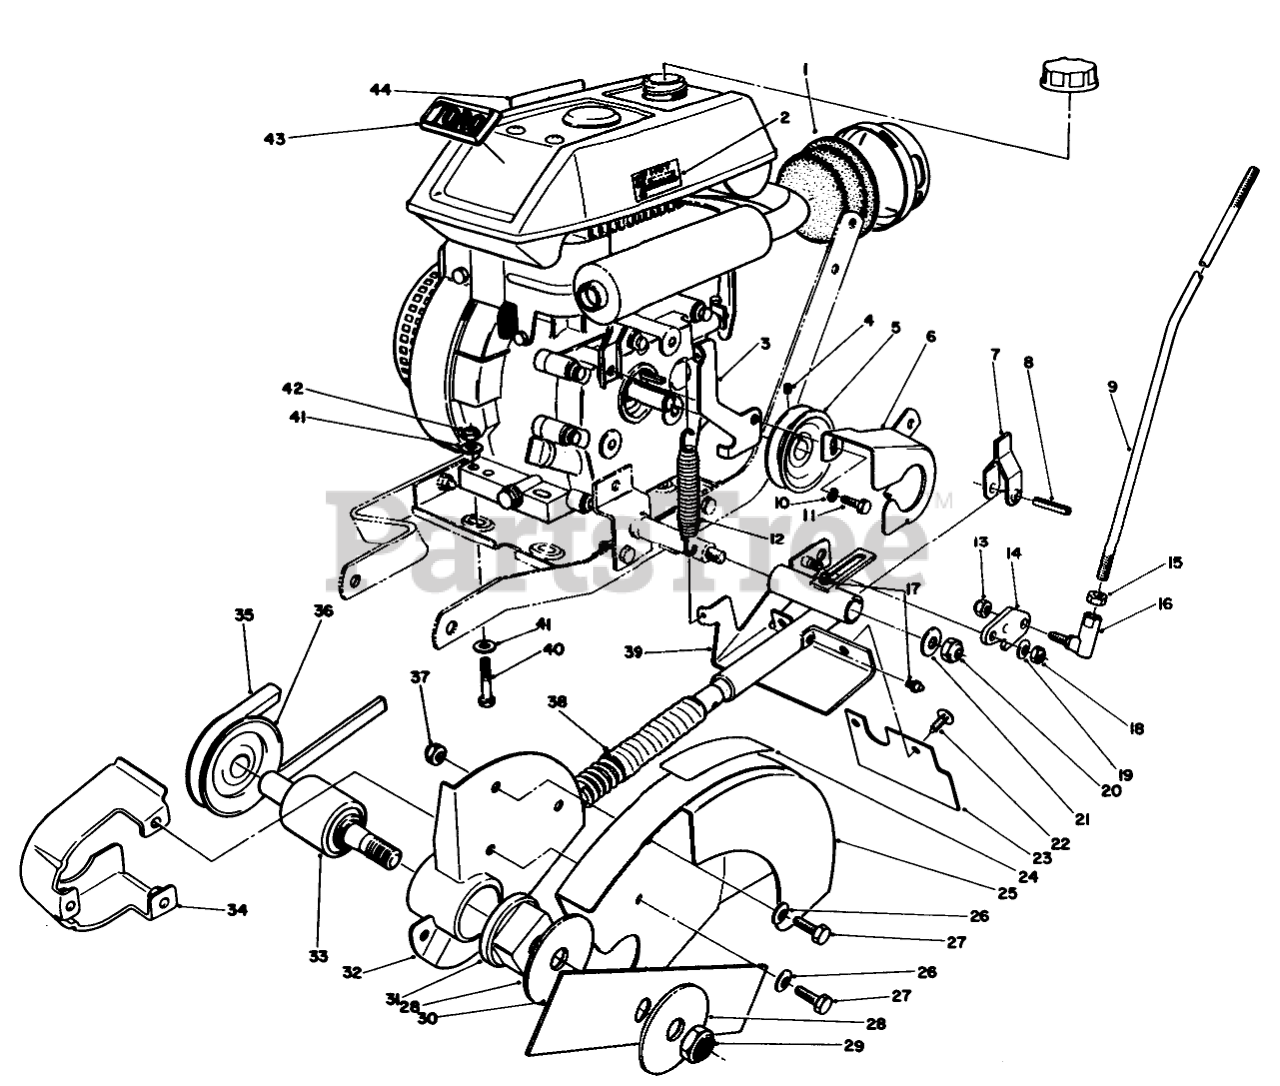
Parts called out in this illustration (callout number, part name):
1	FILTER FOAM
2	Decal-Hot
3	SPRING BRKT R
4	SCREW-SET
5	2HP PULLEY
6	ENG. PULLEY GUARD
7	LEVER WA R
8	SPIROL PIN 1/4" X 1.25"
9	Rod-Lower
10	WASHER-LOCK
11	BOLT
12	EXT. SPRING
13	NUT-LOCK
14	LEVER LOCK WA
15	NUT-HJ
16	BALL JOINT
17	FITTING-GREASE
18	NUT-LOCK, NI
19	WASHER-FLAT
20	NUT-LOCK, NI
21	WASHER-PLAIN
22	PANEL FASTENER
23	RUBBER GUARD
24	BLADE WARNING DECAL
25	Blade Guard Assembly
26	WASHER-BELLEVILLE
27	SCREW-HWHTF
28	WASHER-LARGE
29	NUT-HEX
30	9" EDGER BLADE
31	BRG SHIELD
32	HUB SHAFT WA RO
33	Spindle Assembly
34	PULLEY GUARD WA
35	V-BELT
36	PULLEY-SPINDLE ASM
37	NUT-HEX
38	SPRING & BELLOW ASM
39	PIVOT WA-MASKED 2HP RO
40	SCREW-HH
41	WASHER-PLAIN
42	NUT-LOCK, NI
43	TORO LOGO PLT
44	OPERATING INST DECAL
